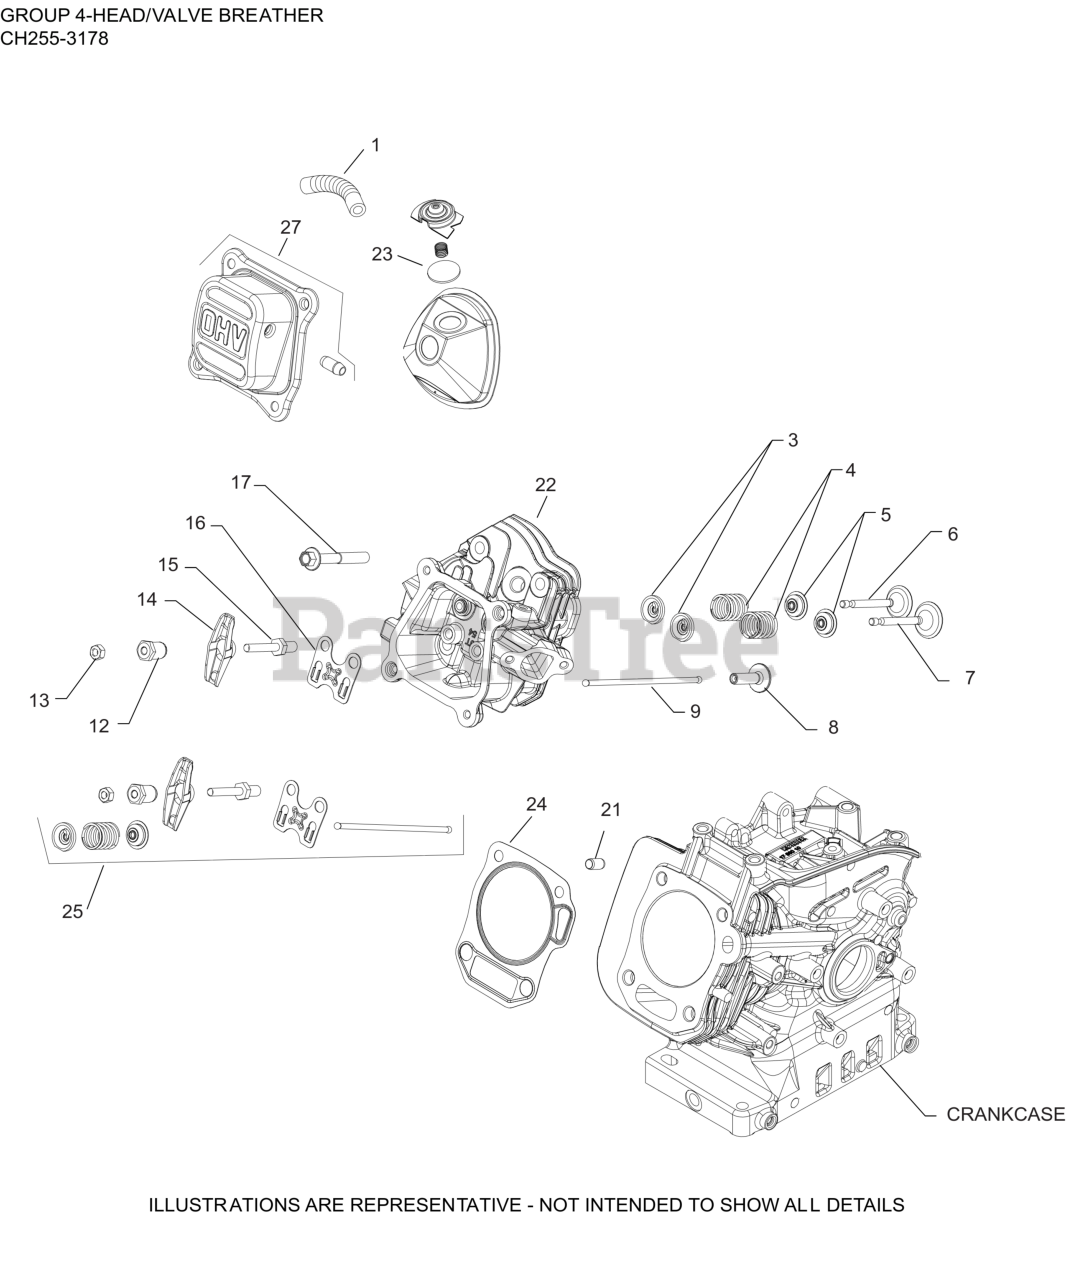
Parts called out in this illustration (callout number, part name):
1	TUBE, BREATHER
3	RETAINER, VALVE SPRING
4	SPRING, VALVE
5	SEAL, VALVE
6	VALVE, EXHAUST
7	VALVE, INTAKE
9	ROD, PUSH-(#1841101S)
12	PIVOT, ROCKER ARM
13	NUT, HEX JAM
14	ARM, ROCKER
15	STUD, ROCKER ARM-USE 14 072 22-S
16	PLATE, PUSHROD GUIDE
17	SCREW, HEX FLANGE CYL HEAD
21	PIN, DOWEL (8mm)
21	DOWEL, CYLINDER HEAD
22	CYLINDER HEAD
23	REED, BREATHER
24	GASKET, CYLINDER HEAD
25	KIT, VALVE TRAIN
27	COVER, VALVE ASSEMBLY
